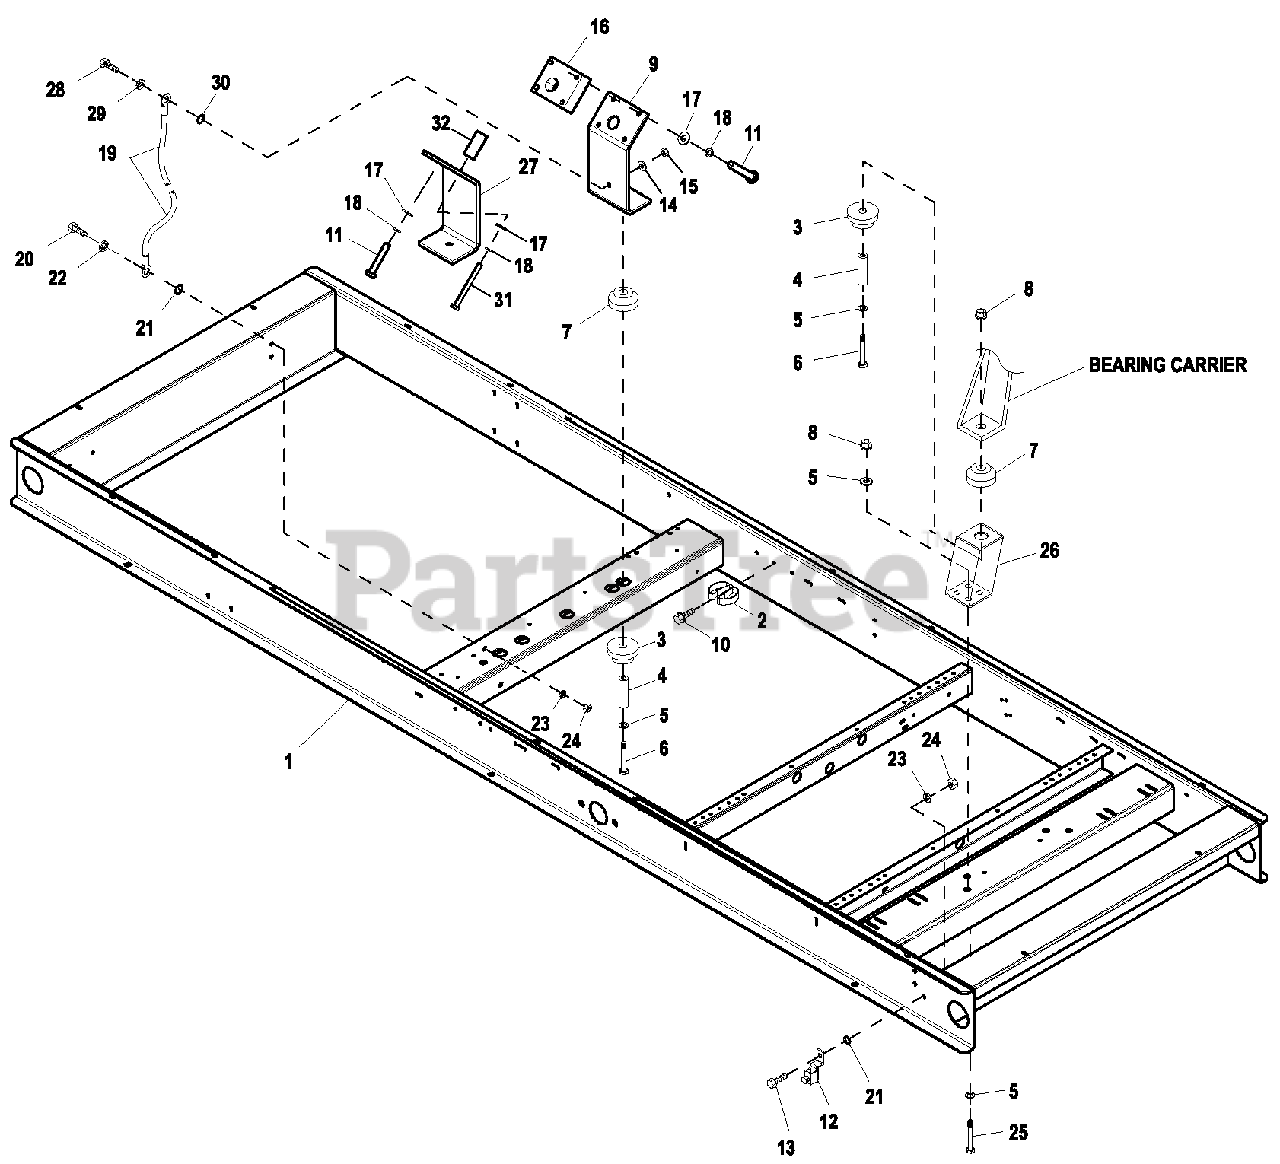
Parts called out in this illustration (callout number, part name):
1	MTG BASE C5 100-130KW 6.8L G8
2	SPRING CLIP HOL D ER .37- 62
3	DAMPENER VIBRATION
4	SPACER .49 X .62 X 1.87 PW D R/ZINC
5	WASHER FLAT M12
6	SCREW HHC M12-1.75X85 G8.8
7	DAMPENER VIBRATION 50 WHITE
8	NUT LOCKING M12-1.75
9	ENGINE SUPPORT 6.8LRH
10	SCREW HHTTM4-0.7X8BP
11	SCREW HHC M10-1.5X60 C8.8
12	LUG SOL DERLESS 3/0-#4 X 13/32 CU
13	SCREW HHC M8-1.25X25 G8.8
14	WASHER FLAT 1/4-M6 ZINC
15	NUT HEX M 6X1.0 G8 YELCHR
16	5.4L RH ENGINE MOUNT SPACER
17	WASHER FLAT 3/8-M10ZINC
18	WASHER LOCK M10
19	ASSY WIRE 14.00"
20	SCREW HHC M8-1.25X30 G8.8
21	WASHER SHAKEPROOF INT 3/8
22	WASHER LOCK M8-5/16
23	WASHER FLAT 5/16-M8ZINC
24	NUT HEXM8-1.25G8 YELCHR
25	SCREW HHC M12-1.75X40 G8.8
26	TOWER GB COMPRO D C5
27	ENGINE MOUNT 6.8LLH SI DE
28	SCREW HHC M6-1.0X30 G8.8
29	WASHER LOCK M6-1/4
30	WASHER LOCK EXT 7/16 STL
31	SCREW HHC M10-1.5X70 C8.8
32	SPACER .41 X .7 5 X 1 .6 8 ST/ZNC
